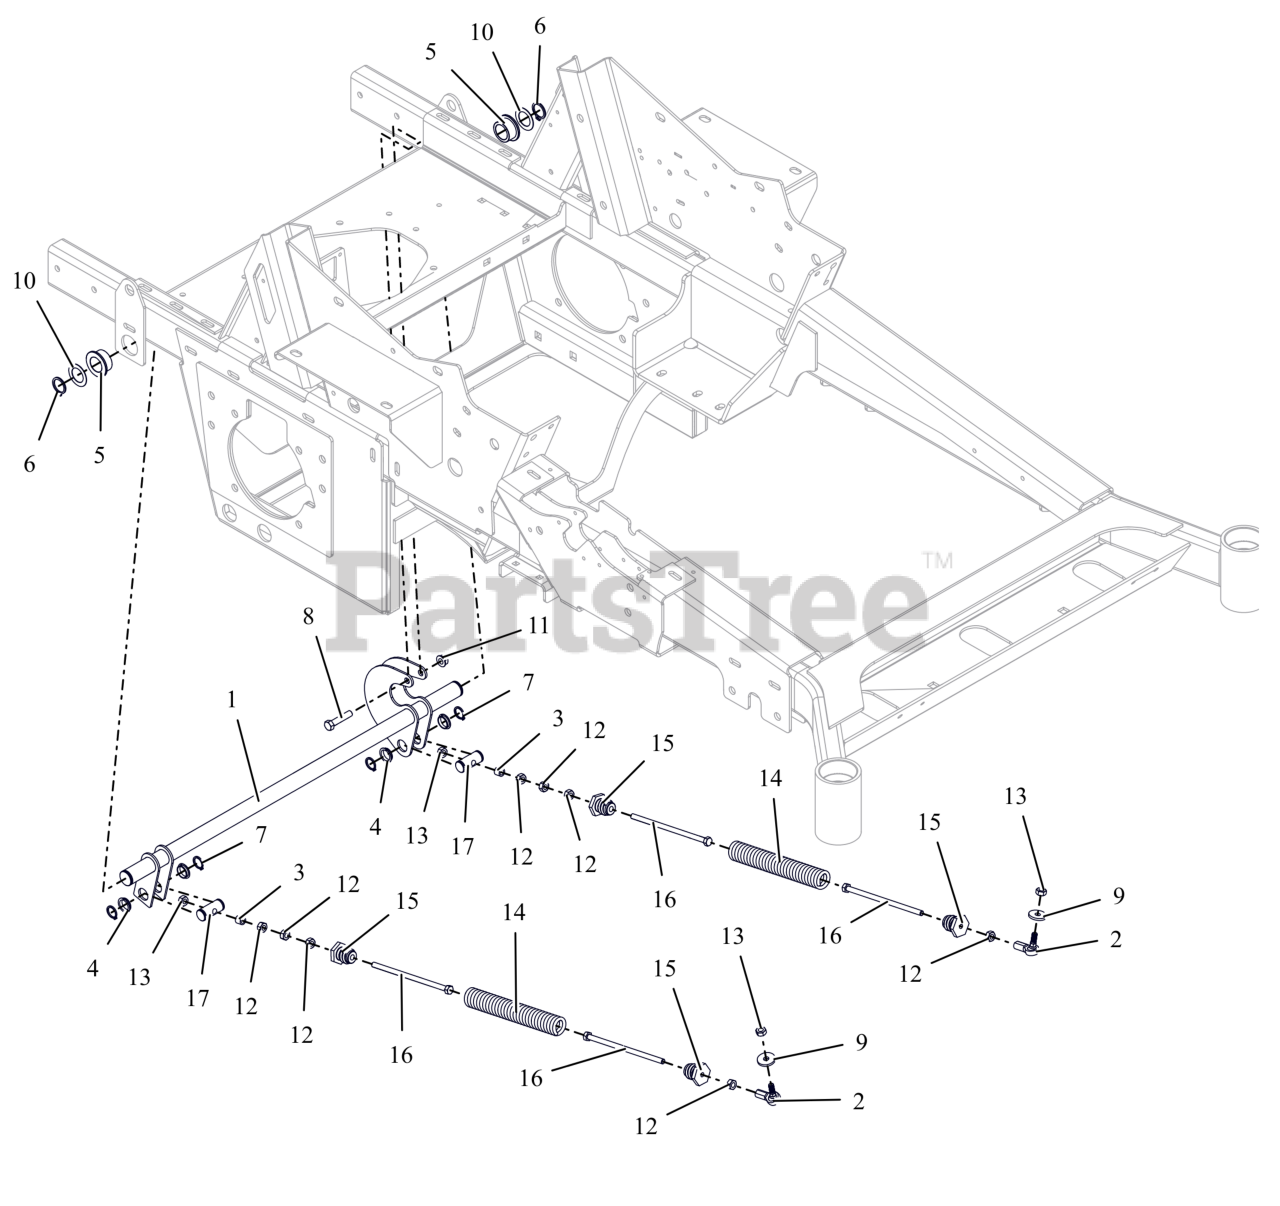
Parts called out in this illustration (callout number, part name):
1	WLDMT, BRAKE REAR PIVOT SHAFT
2	LINKAGE, BALL JOINT .312-24 UNF RH STUD
3	SPACER .50 X .32 X .42
4	BSHG, POLYLINER- .75 SNAP-IN
5	BSHG-FLG1.020X1.385X.75X1.75NY
6	RG-RTNG-EXT 1.00X.078
7	RG-RTNG-EXT .689X.078
8	BLT, HEX .38-16X1.75F G5 ZCC
9	WSHR, FLT .340X1.125X.135 ZCC
10	WSHR-HDND-THRUST 1.00X1.55X.03
11	NUT-LK-CTR-FLG .375-16 GF ZCC
12	NUT, HEX-JAM .3125-24 ZCC
13	NUT-CTRLK .31-24 YWZC
14	SPRG, EXTENSION .063 X .653 X 2.755
15	PLUG, SPRG
16	BLT-HEX.31-24X6.5 FULTHD G5ZCC
17	TRUNNION, BRAKE PIVOT
